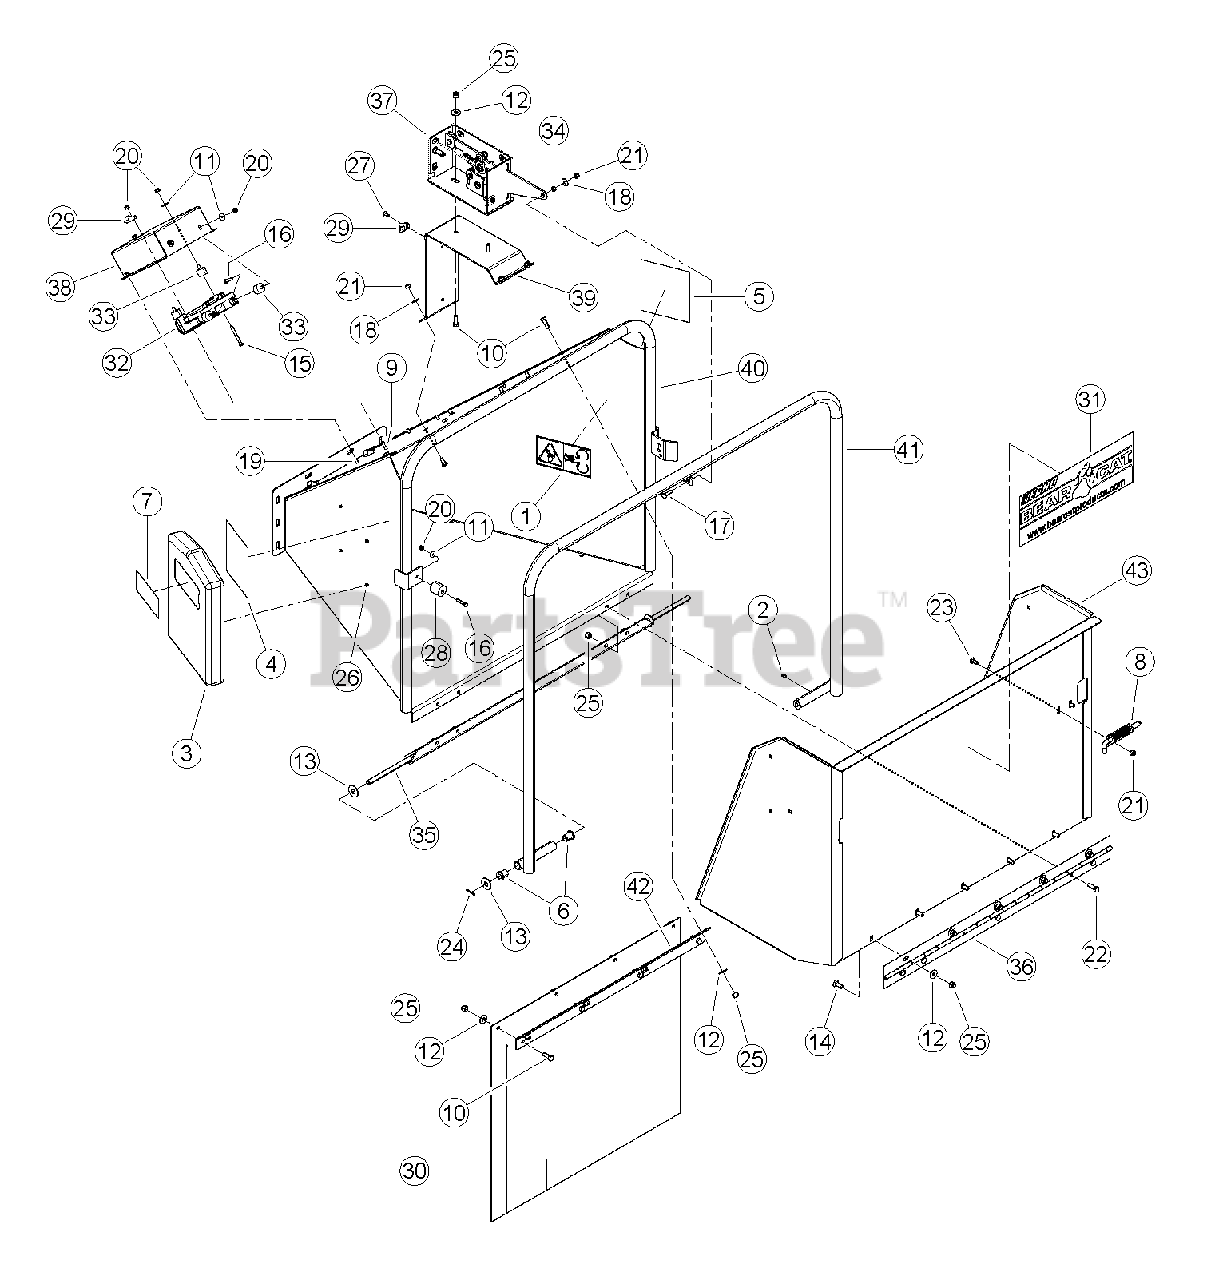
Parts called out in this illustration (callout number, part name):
1	DECAL, BLADE DANGER ISO
2	FITTING, 1/4 SELF-TAP GREASE
3	CONTAINER, INSTRUCTION MANUAL
4	DECAL, FEED POSITION
5	DECAL, FEED POSITION
6	BUSHING, 1/2 X 1 FLANGE LUBE
7	DECAL, MULTILINGUAL MANUAL
8	LATCH, RH HINGE
9	BOLT, 1/4 X 1 HEX HD GR5 ZP
10	BOLT, 3/8 X 1 HEX HD GR5 ZP
11	WASHER, 1/4 FLAT ZP
12	WASHER, 3/8 FLAT ZP
13	WASHER, 1/2 FLAT ZP
14	BOLT, 3/8 X 1 CRG GR5 ZP
15	BOLT, 1/4 X 2-1/4 HEX HD GR5 ZP
16	BOLT, 1/4 X 1-1/4 HEX HD GR5 ZP
17	BOLT, 5/16 X 1 HEX HD GR5 NC ZP
18	WASHER, 5/16 FLAT ZP
19	BOLT, 1/4 X 5/8 HEX HD GR5 ZP
20	NUT, 1/4 NE NYLOCK ZP
21	NUT, 5/16 NE NYLOCK ZP
22	BOLT, 3/8 X 1-1/4 HEX HD GR5 ZP
23	BOLT, 5/16 X 3/4 CRG GR5 NC ZP
24	PIN, 1/8 X 1 COTTER ZP
25	NUT, 3/8 NE NYLOCK ZP
26	RIVET, AL BLIND 1/4 X 1/2 DOME HEAD
27	RIVET, AL BLIND 1/4 X 3/4 DOME HEAD
28	BUMPER, RECESSED RUBBER
29	CLAMP, CABLE MOUNT
30	FLAP, CHUTE
31	DECAL, BEARCAT WEB
32	CONTROLLER, PLUS 1 CHIPPER
33	BUMPER, 1 OD. W/1/4 STUD
34	SPACER, IDLER PIVOT
35	WELDMENT, CONTROL PIVOT
36	HINGE, EXTENSION TRAY
37	ASSEMBLY, SWITCH BOX
38	ENCLOSURE, PLUS 1 MOUNT
39	MOUNT, SWITCH BOX
40	WELDMENT, CHIPPER CHUTE
41	WELDMENT, CONTROL ARM
42	SUPPORT, CHIPPER FLAP
43	WELDMENT, EXTENSION TRAY W/O TABS
